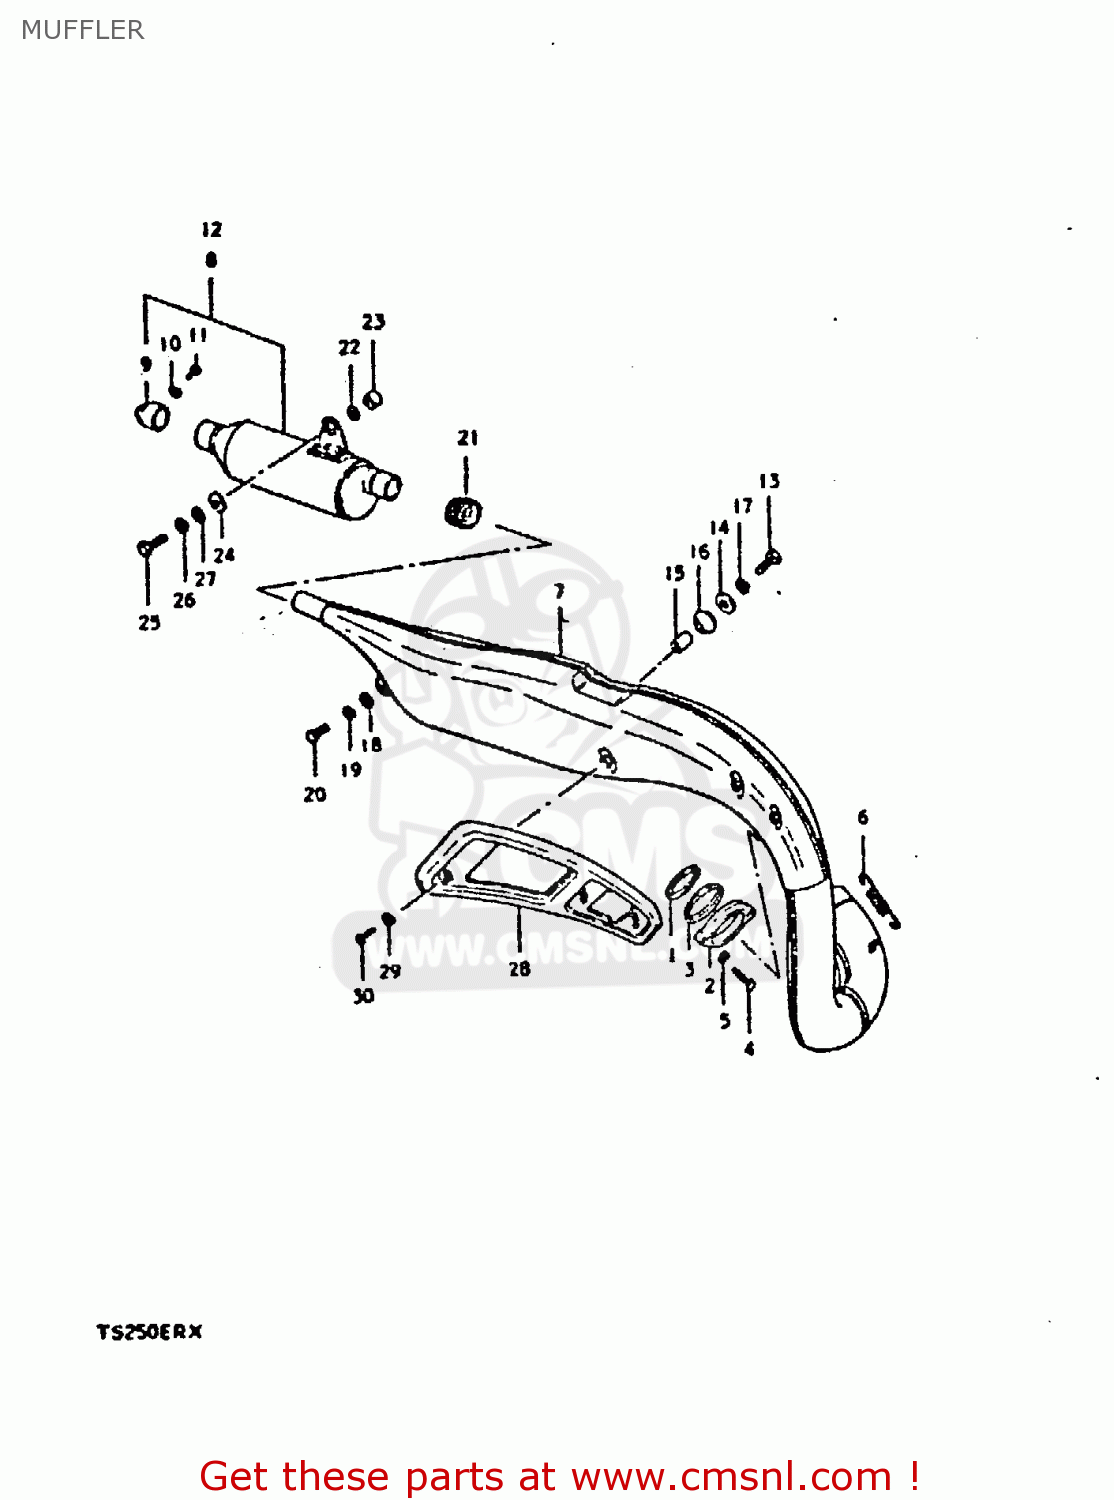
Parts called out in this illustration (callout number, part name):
1	GASKET,EXHAUST PIPE (NAS)
2	CLAMP,EXHAUST PIPE
3	GASKET,EXHAUST PIPE
4	BOLT
5	LOCK WASHER
6	SPRING
7	MUFFLER ASSEMBLY,FIRST
8	MUFFLER, 2ND
10	LOCK WASHER
11	SCREW
13	BOLT (8X30)
14	WASHER (8.7X22X2)
15	SPACER (8X12X15)
16	DAMPER,MUFFLER,FR
17	LOCK WASHER
18	WASHER
19	LOCK WASHER
20	BOLT
21	CONNECTOR,MUFFLER
22	WASHER
23	SPACER
24	CUSHION
25	BOLT
26	LOCK WASHER
27	WASHER
28	COVER,MUFFLER
29	LOCK WASHER
30	SCREW
